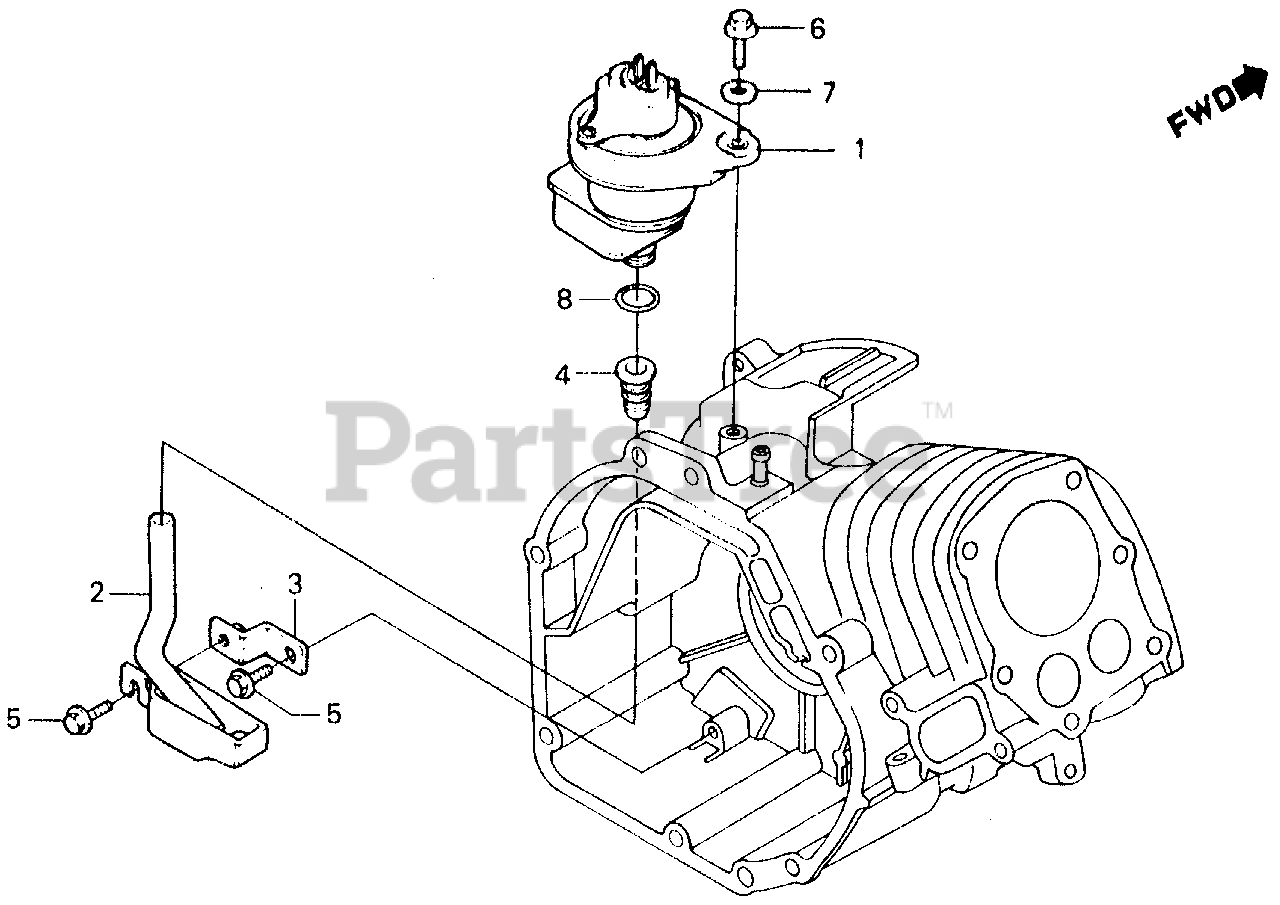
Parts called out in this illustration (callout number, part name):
1	SWITCH ASSY., UNIT (NOT AVAILABLE)
3	PLATE, OIL CUP SETTING (NOT AVAILABLE)
4	TUBE, OIL ALARM
5	BOLT, FLANGE (5X10)
6	BOLT, FLANGE (5X16)
7	WASHER, STOPPER (5MM)
8	O-RING (11X2.0)
